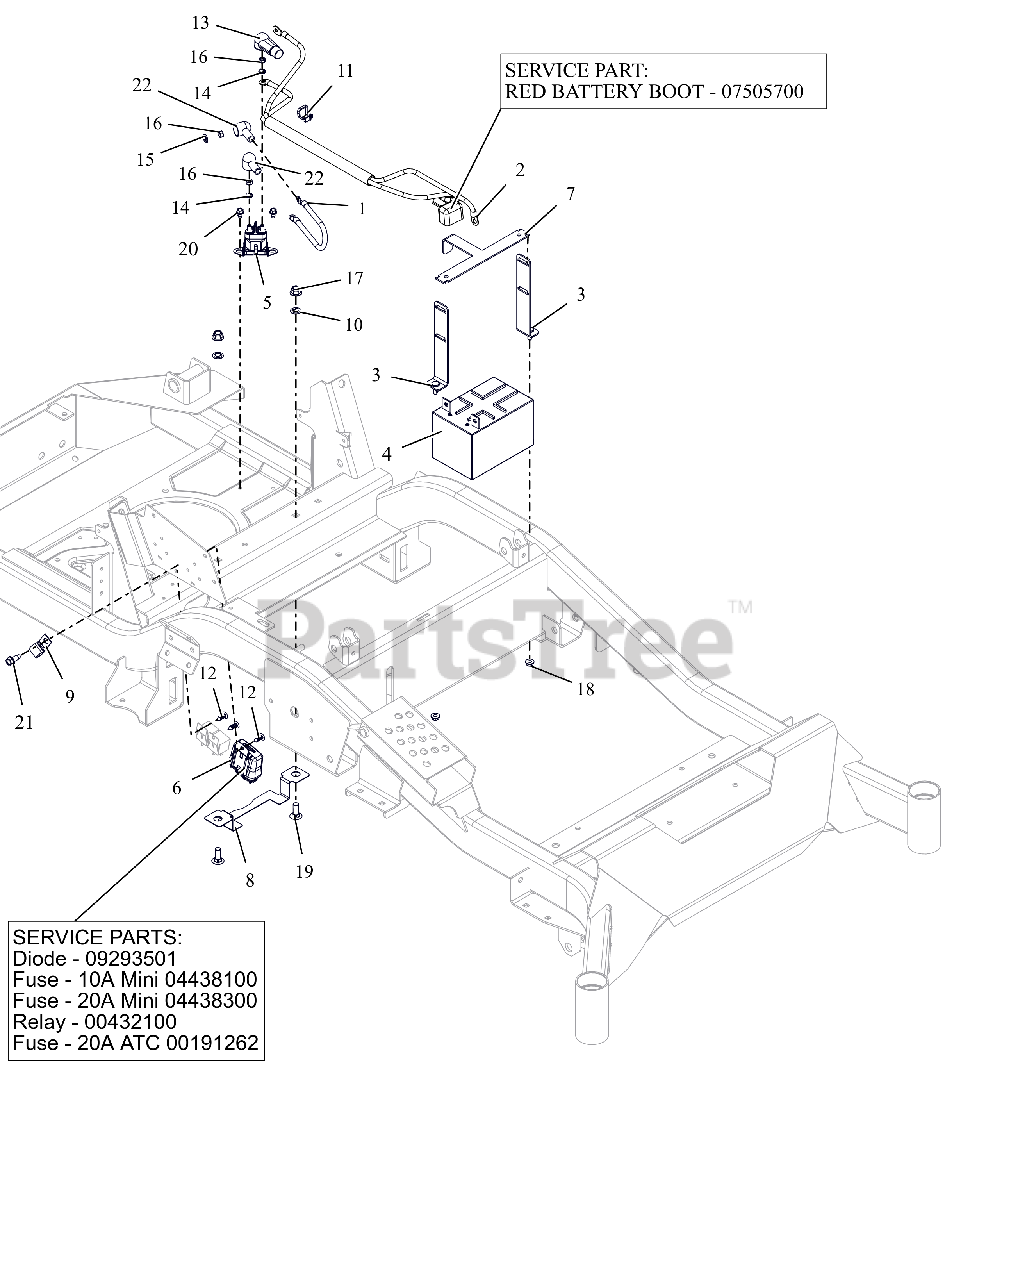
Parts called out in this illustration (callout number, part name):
1	CABLE, POS W/(2)1/4 RING 9.0LG
2	HARNESS, BATTERY HD
3	WMT,BATTERY MOUNT HOLD DOWN
4	BATTERY, 12V 12A-190CCA
5	SOLENOID, STARTER (SEALED)
6	HARNESS, WIRE
6	DIODE, CONNECTOR SHELL
6	FUSE,10 AMP MINI-ATC
6	FUSE,20 AMP MINI ATC
6	RELAY,SEALED W/DIODE
6	FUSE, 20 AMP BLADE S/O
7	BRKT, BATTERY TIE DOWN
8	GUARD, ELECTRICAL HARNESS
9	J-CLAMP
10	NUT-PUSH .38 DIA. PAL ZINC
11	CABLE TIE W/ TREE (.25 HOLE)
12	RIVET, .25 NYLON PANEL
13	BOOT, .65ID POS
14	WSHR,LK-EXT.262X.502X.026 ZCC
15	WSHR,LK-REG .312X.078 ZCC
16	NUT-STD M6-1.0 ZCC
17	NUT,NYL-FLG .38-16 GF ZCC
18	NUT-LK-TOP-FLG .250-20 GF ZCC
19	BLT, RHSN .38-16X1.00 G5 ZCC
20	SCR,TAP .25-20X.375 HWH TR ZCC
21	SCR,TAP .312-18X.75 HWH TR ZCC
22	BOOT, EYELET TERMINAL
23	INSULATOR
